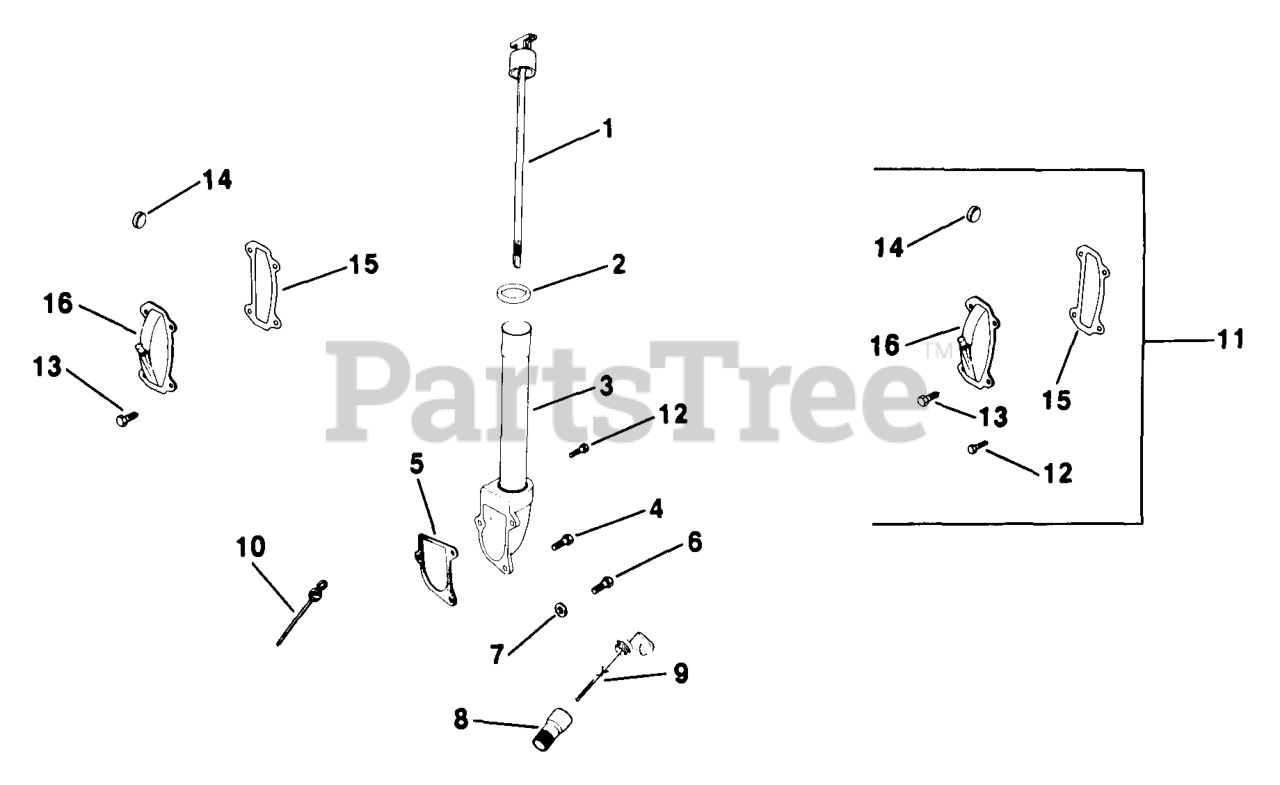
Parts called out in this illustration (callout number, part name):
1	DIPSTICK - DISCONTINUED
4	SCREW - DISCONTINUED
5	GASKET, OIL FILL ADAPTER
